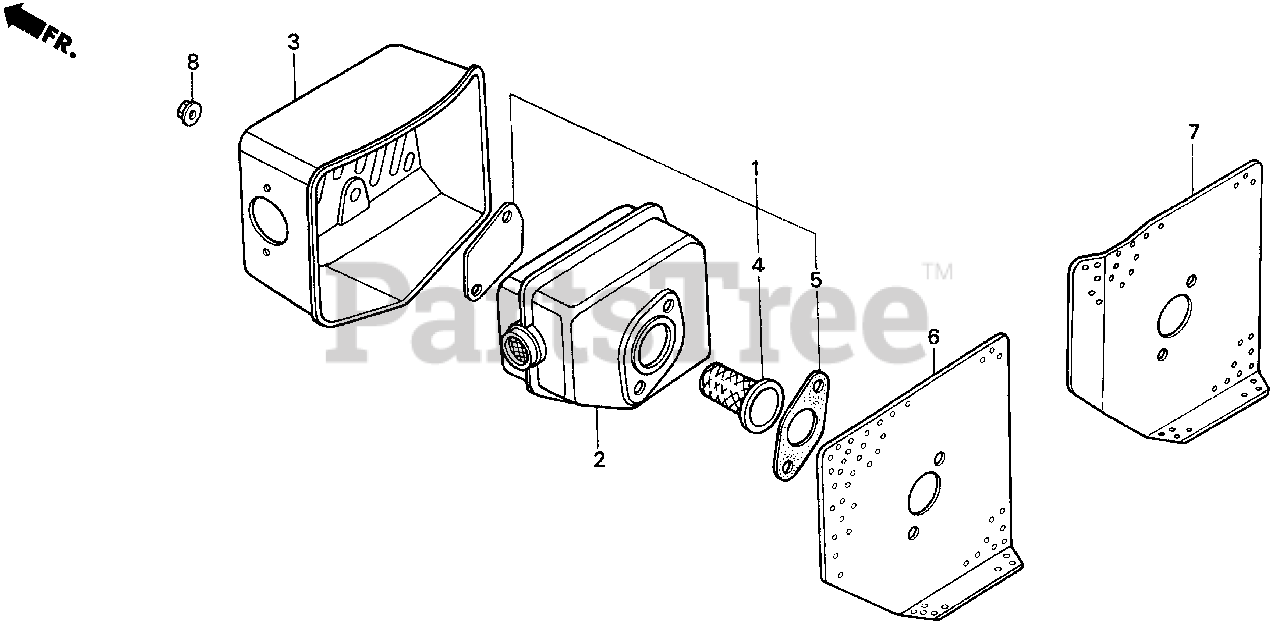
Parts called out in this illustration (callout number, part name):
1	ARRESTER KIT, SPARK
2	MUFFLER
3	PROTECTOR, MUFFLER
4	ARRESTER KIT, SPARK
5	GASKET, MUFFLER
7	GASKET, MUFFLER
8	NUT, SELF-LOCK (6MM)
